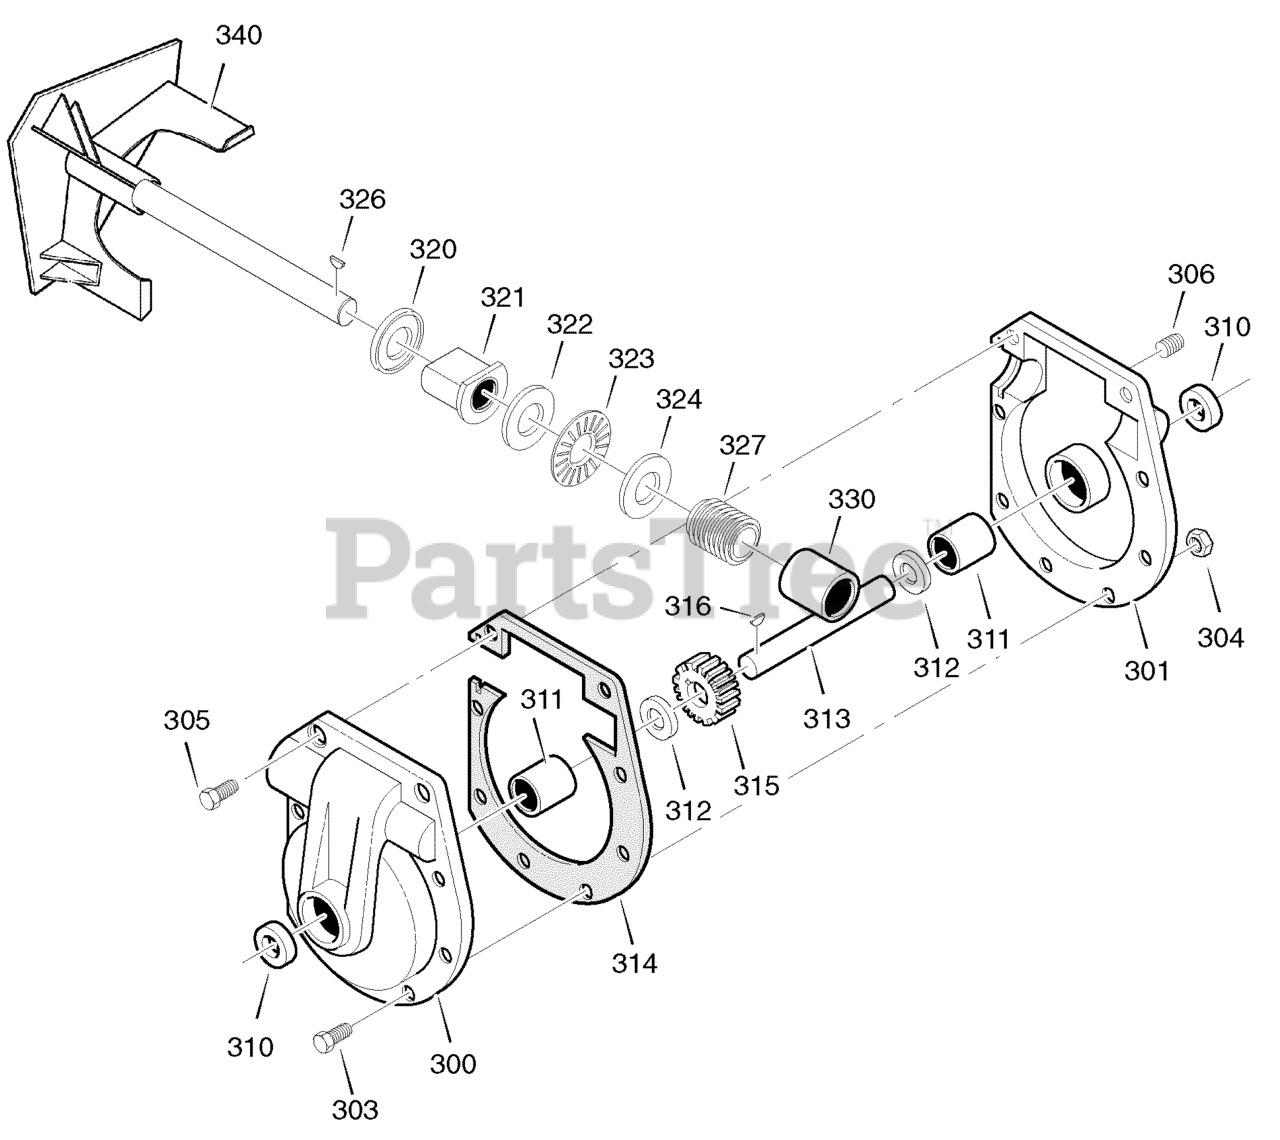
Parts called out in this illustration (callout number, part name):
300	CASE, GEAR, RH
301	CASE, GEAR, LH
303	SCREW, 5/16-24 x 1.00
304	NUT, 5/'16-24
305	SCREW, 5/16-24 x 1.50
306	PLUG, PIPE 0.25-18
310	SEAL, OIL
311	BEARING, SLEEVE
312	WASHER, FLAT
313	SHAFT, AUGER OUTPUT
314	GASKET, GEAR BOX
315	WORM GEAR
316	KEY, WOODRUFF #91
320	RING, QUAD 0.924 ID
321	BEARING, FLANGE
322	WASHER, FLAT
323	BEARING, ROLLER
324	WASHER, FLAT
330	BEARING, SLEEVE
